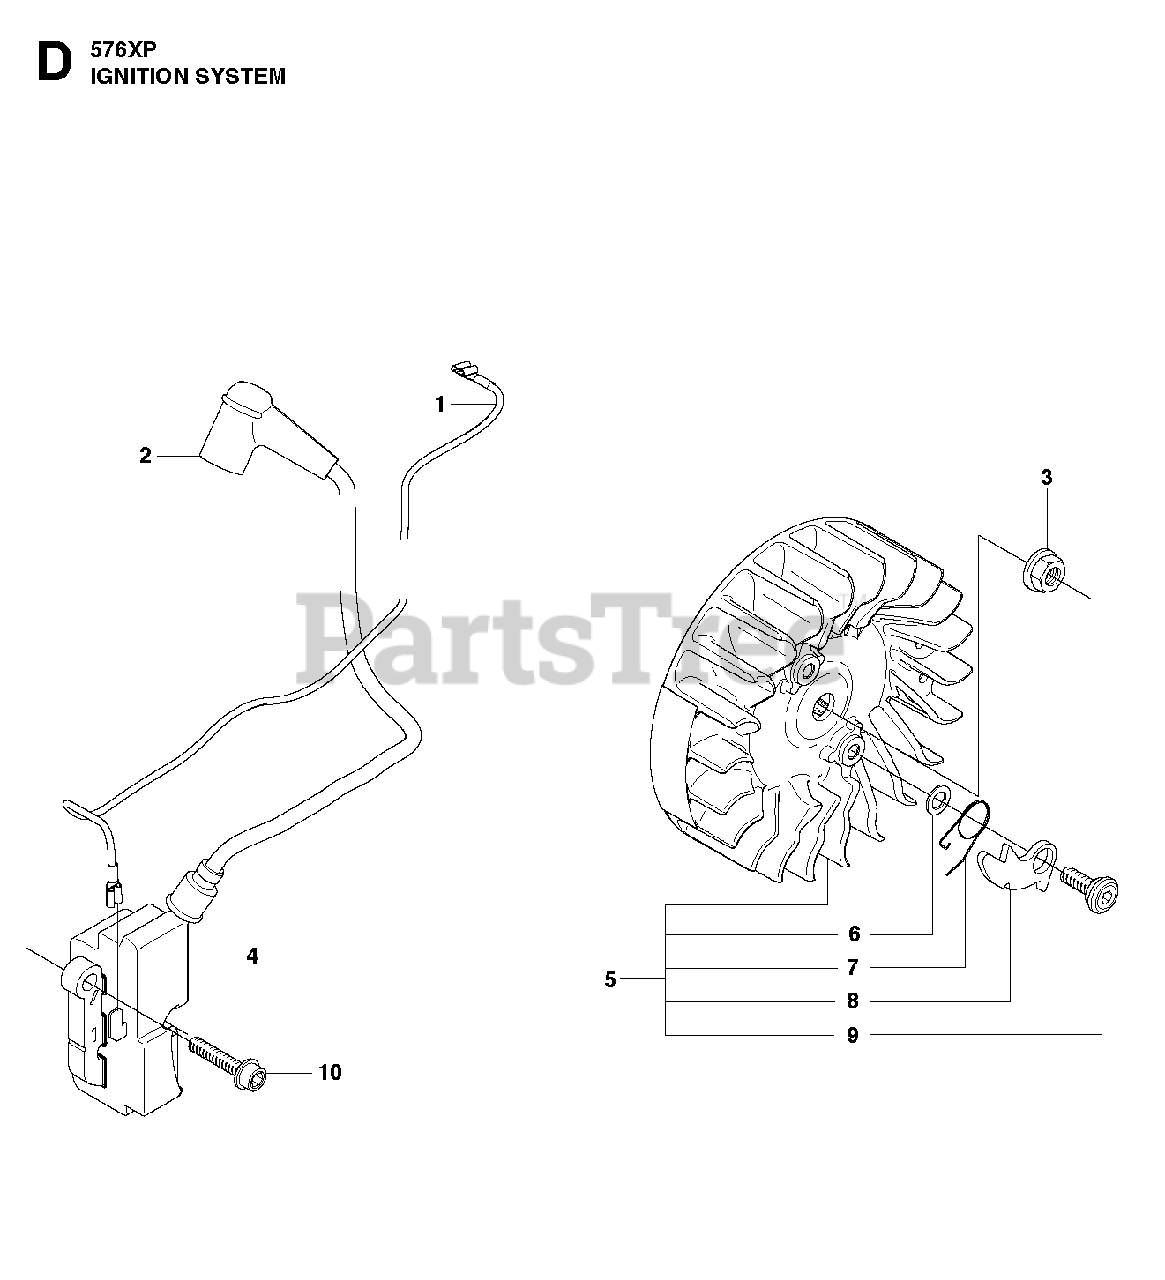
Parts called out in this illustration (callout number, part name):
1	SHORTING LEAD
2	SPARK PLUG CONN. KIT
3	NUT W/ WASHER
4	IGNITION MODULE
6	WASHER
7	SPRING
8	PAWL
9	SCREW M5X14
